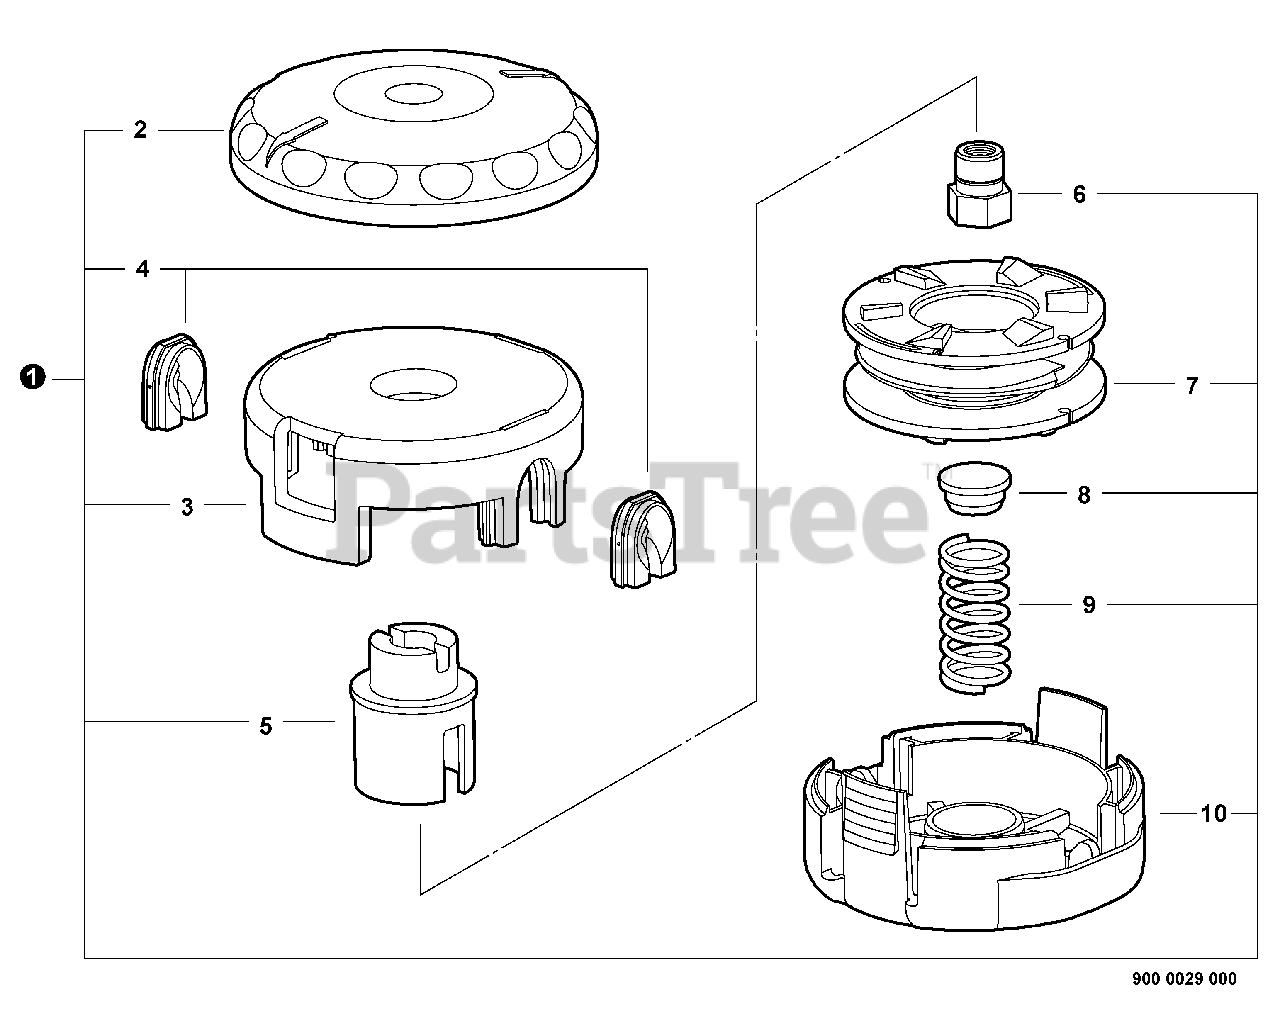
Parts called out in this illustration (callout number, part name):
1	SPEED-FEED 375 TRIMMER HEAD
3	COVER, SPOOL
6	ARBOR
8	CAP
9	SPRING
